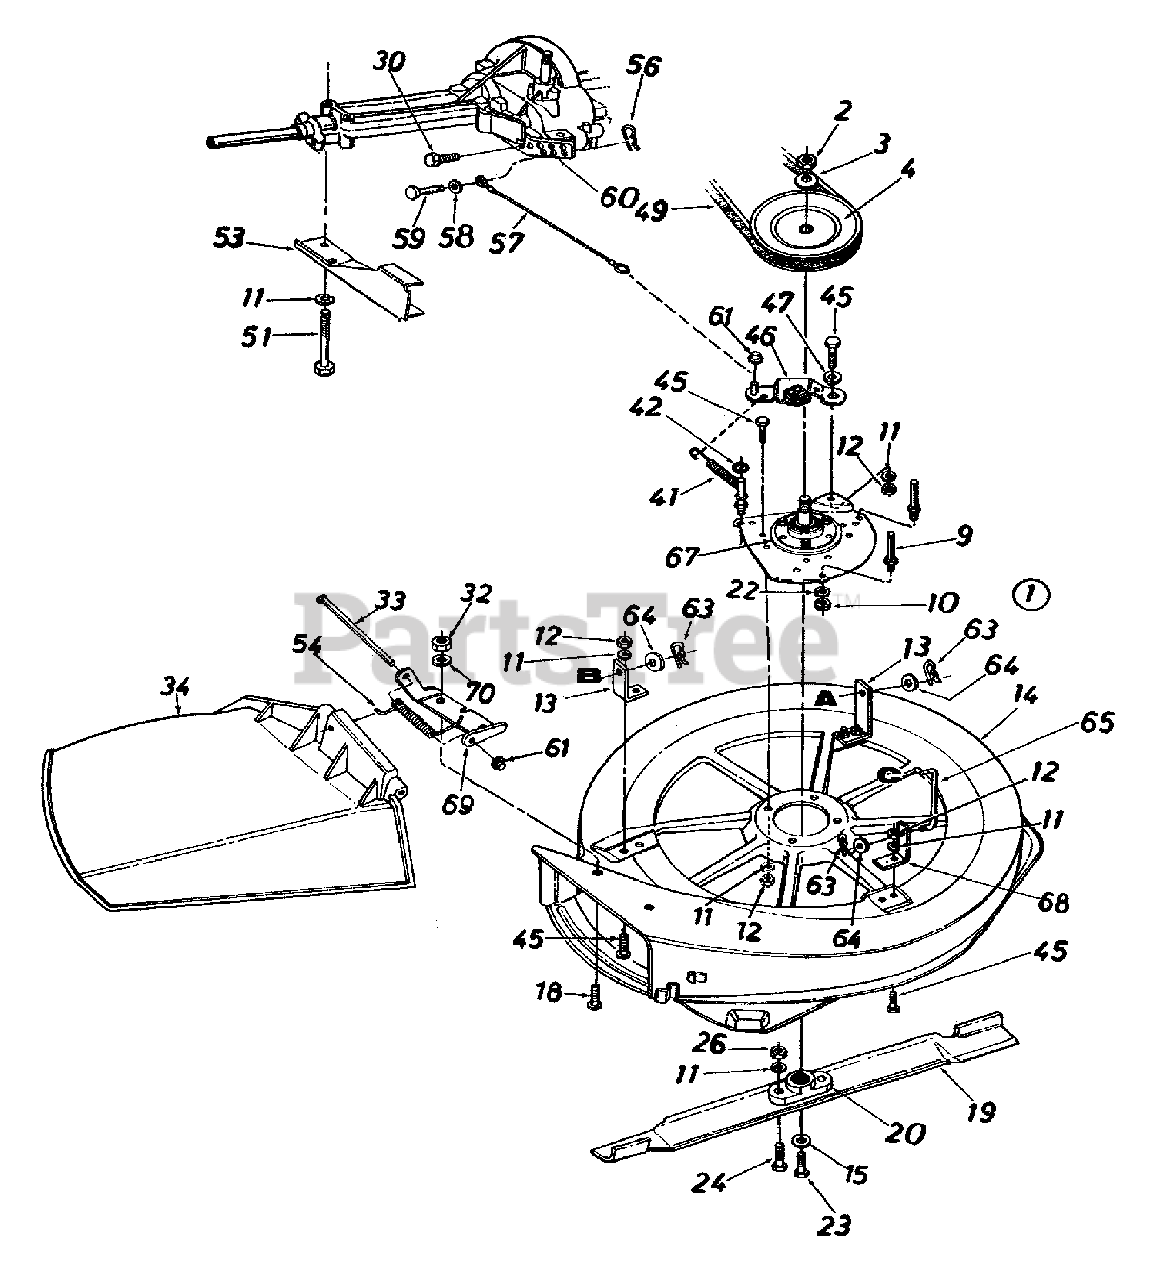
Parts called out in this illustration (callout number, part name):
1	30" S.D. Deck Ass'y. Comp
2	Hex Jam Nut 5/8-18 Thd.
3	Bell-Wash. .630" I.D. x 1.25"
4	5/8 V-Pulley .75" I.D. x 7"
9	Stud 3/8-16 x 2.75" Lg.
10	Hex Jam Nut 3/8-16 Thd.
11	L-Wash. 5/16" I.D.
12	Hex Nut 5/16-18 Thd.
18	Hex Cap Scr. 1/4-20 x .625" Lg.
19	30" High Lift Blade
20	Blade Adapter
22	L-Wash. 3/8" I.D.
23	Hex Bolt 3/8-24 x 1.0
24	Hex Bolt 5/16-24 x 1.0" Lg.
26	Hex Nut 5/16-24 Thd.
30	Hex Bolt 1/4-20 x .50" Lg.
32	Hex Nut 1/4-20 Thd.
33	Hinge Pin
34	Chute Ass'y. Comp.
41	Extension Spring .5" O.D. x 3.2" Lg.
42	Push Speed Nut
45	Hex Bolt 5/16-18 x .75"
46	Blade Brake Brkt. Ass'y.
47	Shoulder Spacer .500" Dia.
49	"V"-Belt
51	Hex Bolt 5/16-18 x 2.75"
56	Int. Cot. Pin 5/16" Dia.
57	Brake Cable 9.75" Lg.
58	Fl-Wash. .281" I.D. x .50"
59	Clevis Pin 1/4" Dia.
63	Int. Cotter Pin 1/2" Dia.
64	Fl-Wash. .531" I.D. x .930"
65	Deck Link 3.9" Lg.
67	Blade Spindle Ass'y. Comp.
68	Weld Bracket
69	Hinge Mtg. Brkt.
70	Bell-Wash. 1/4" I.D.
